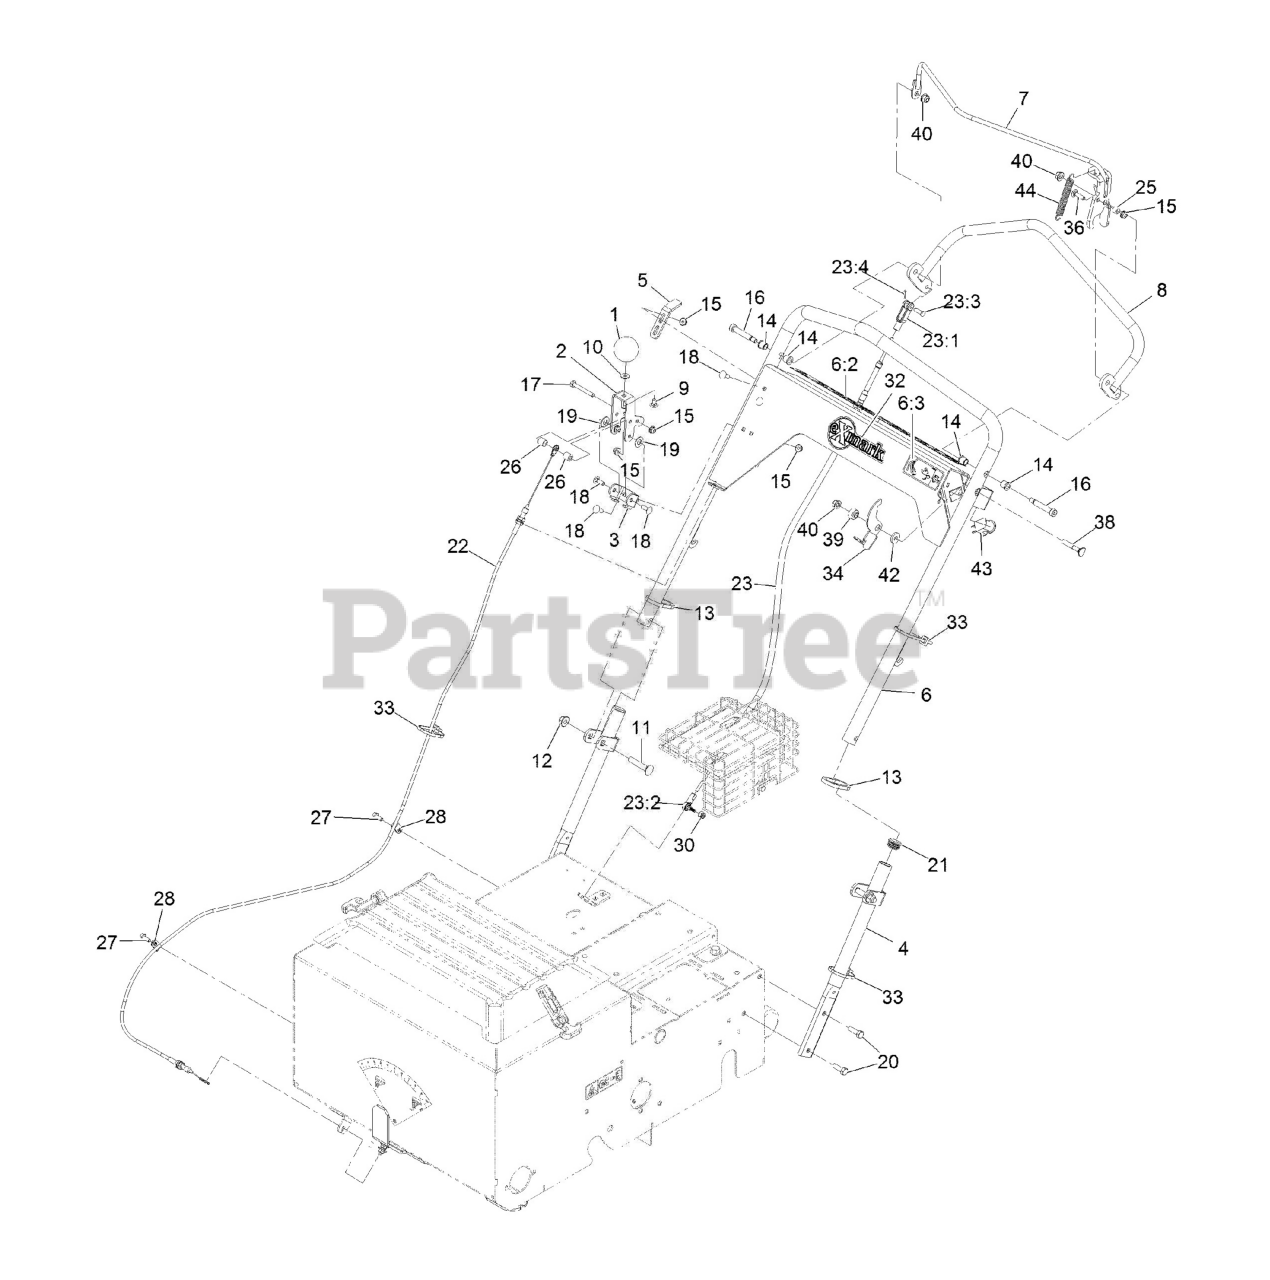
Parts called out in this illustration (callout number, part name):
1	KNOB-RATE, FLOW
2	LEVER-ADJUST, FLOW
3	BRACKET-ADJUST, FLOW
4	HANDLE-LOWER
5	BRACKET-ADJUST, DRIVE
6:2	DECAL-CONTROL PANEL, SEED
6:3	DECAL-SAFETY LATCH
7	BAIL-CLUTCH
8	HANDLE-DRIVE
9	SCREW-CARR
10	WASHER-FLAT
11	SCREW-CARR
12	NUT-HF, NI
13	RING-HANDLE LOCK
14	BEARING
16	SCREW-SHOULDER
17	SCREW-HH
18	BOLT-CARR
19	WASHER-PLAIN
20	SCREW-HH
22	CABLE-FLOW, SEED
23	CABLE-PUSH PULL
23:2	Ball Joint
23:3	Pin-Clevis
23:4	PIN-COTTER
27	SCREW-HH
28	CLAMP-R
30	NUT-LOCK
32	DECAL-EXMARK LOGO
33	TIE-CABLE
34	LATCH-BAIL
36	SCREW-CARR
39	BUSHING-STEPPED
40	NUT-HF, NI
42	WASHER-FLAT
43	SWITCH-BAIL
